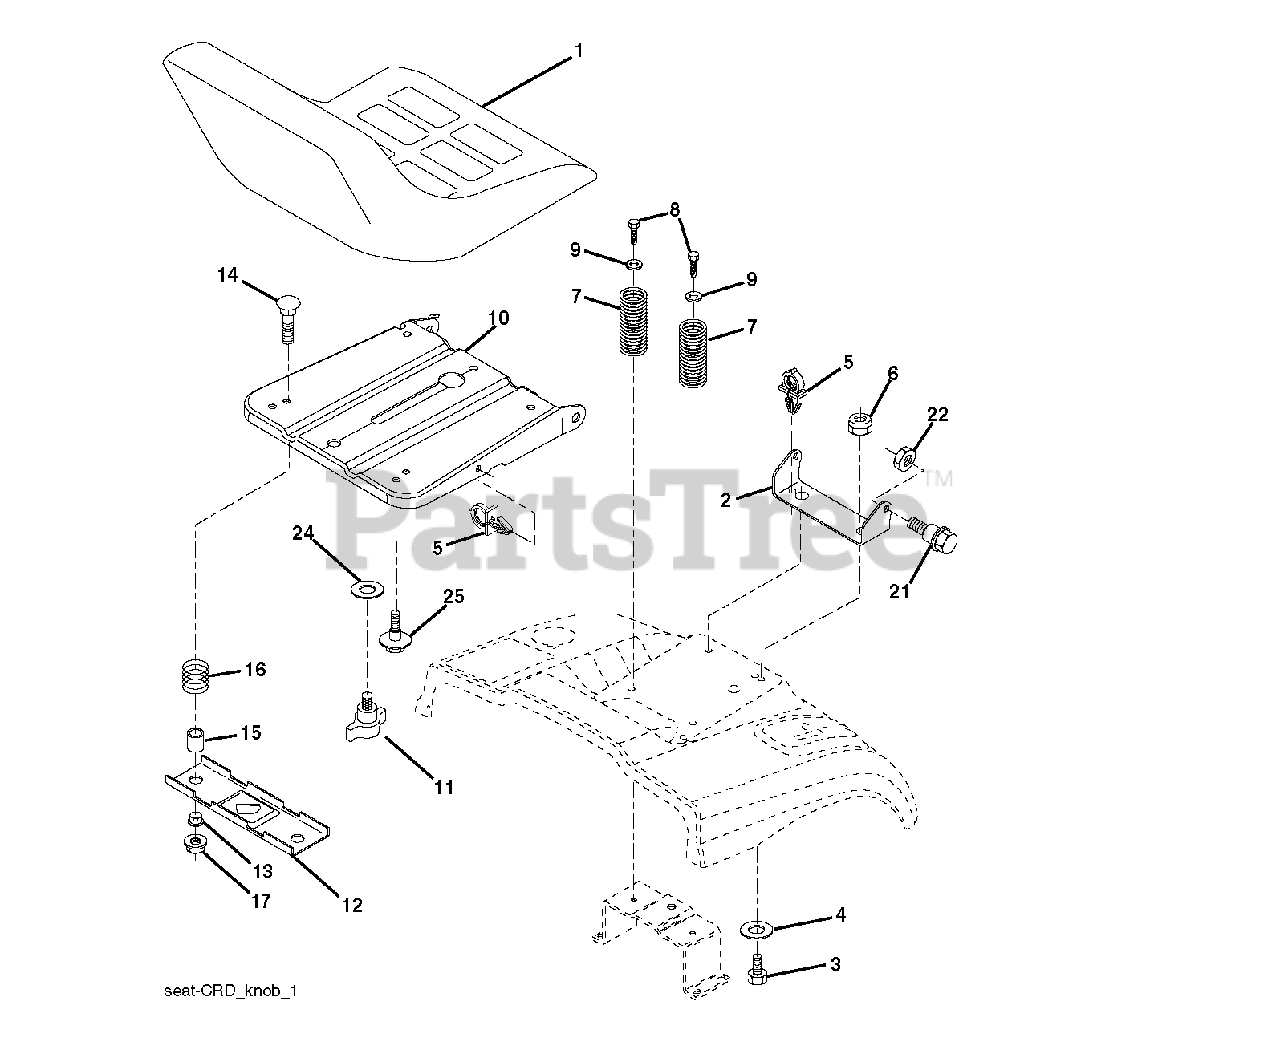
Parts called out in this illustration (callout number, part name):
2	SEAT PIVOT BRKT
4	WASHER PM
5	PUSH CLIP
6	NUT
7	SPRING COMPRESSION
8	SCREW 3/8-16X1
9	WASHER
10	PAN.ASM.SEAT.1SLOT
11	KNOB.SEAT.ADJ.WINGNUT
12	BRKT.MNTNG.SWITCH.SEAT
14	BOLT.ROUND.HEAD.SQUARE.NECK
15	SPACER SPLIT 28X.96
17	NUT T
21	BOLT.SHOULDER.5/16-18
22	NUT.71038.31-18.HEX.NYLOCK
25	BOLT,SHOULD
